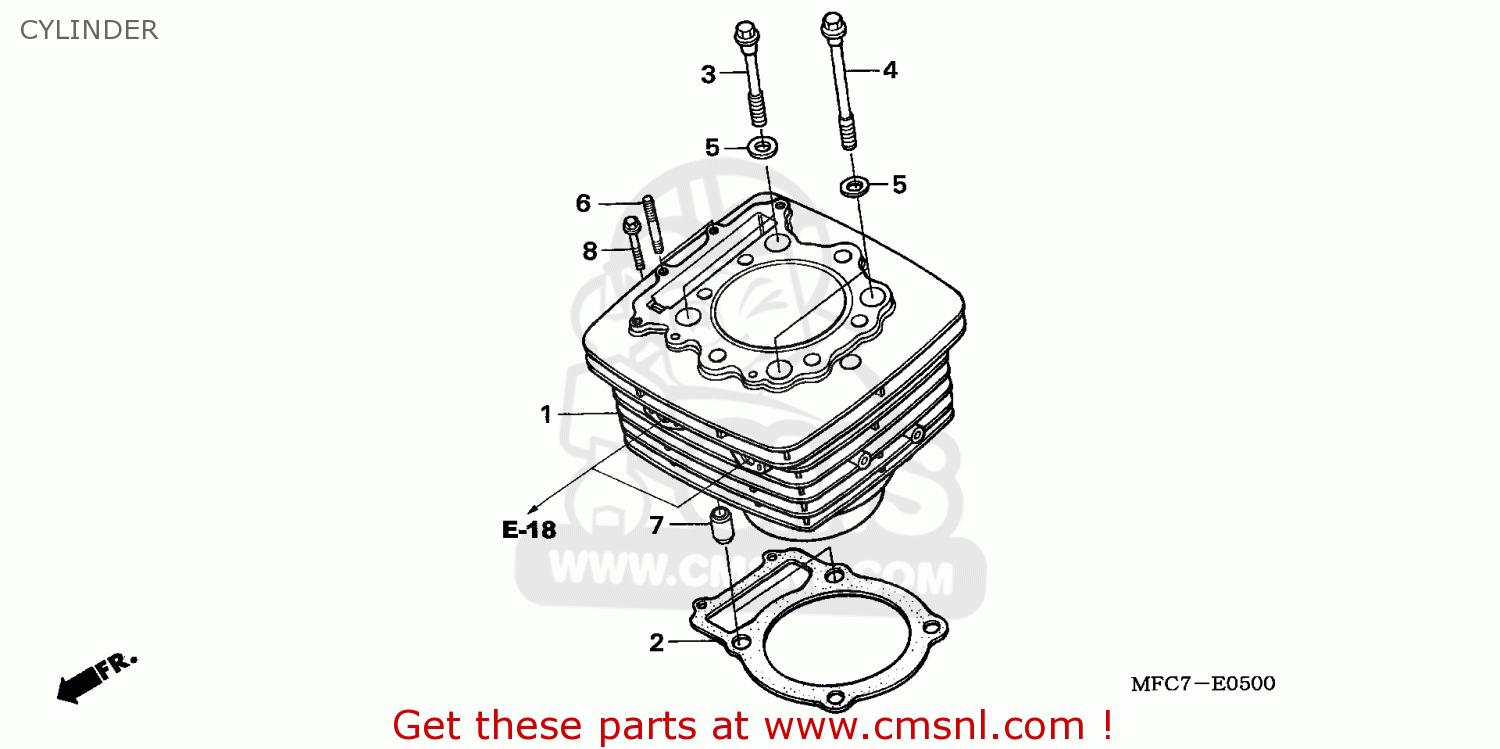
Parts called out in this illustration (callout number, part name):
1	CYLINDER COMP
2	GASKET,CYLINDER (NAS)
3	BOLT,FLANGE,10X66
4	BOLT,FLANGE 10X11
5	WASHER,PLAIN,10MM
6	BOLT,STUD,6X22
7	DOWEL,PIN,12X20
8	BOLT,FLANGE,6X32
